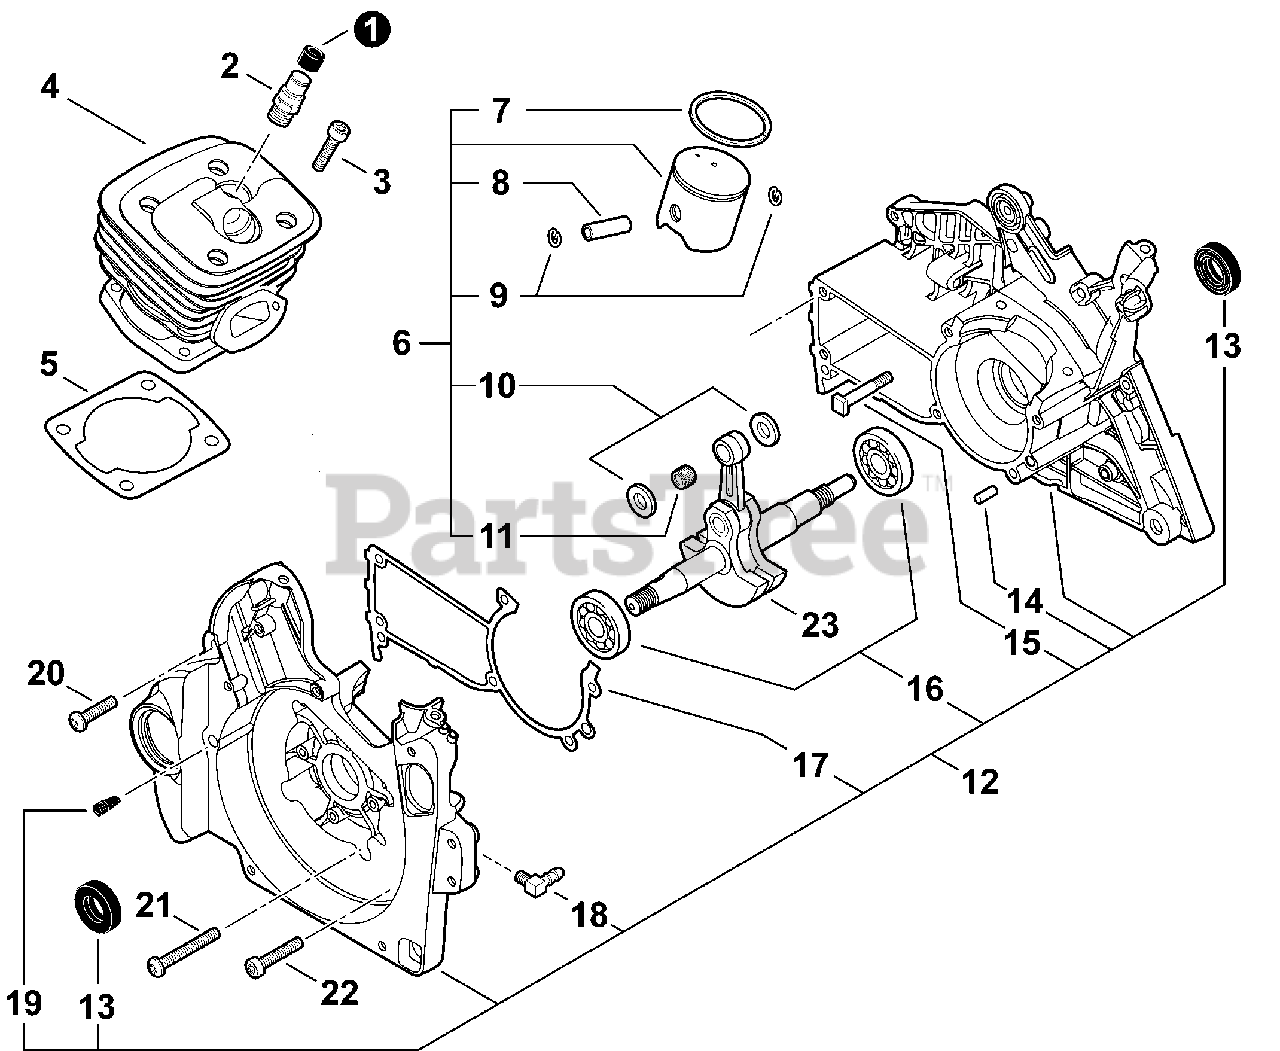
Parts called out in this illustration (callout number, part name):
1	COVER, DUST
2	DECOMPRESSION ASY
3	SCREW - 5×25
4	CYLINDER
5	GASKET, CYLINDER
6	PISTON KIT
7	RING, PISTON
8	PIN, PISTON
9	RING, RETAINING - 1
10	WASHER, THRUST - 1
11	BEARING, NEEDLE
12	CRANKCASE KIT
13	SEAL, OIL
14	PIN, DOWEL
15	STUD, GUIDE BAR
16	BEARING, BALL
17	GASKET, CRANKCASE
19	VALVE, CHECK
20	SCREW - 5×20
21	SCREW - 5×35 -- TAPPING
22	SCREW - 5×25
23	CRANKSHAFT ASY
